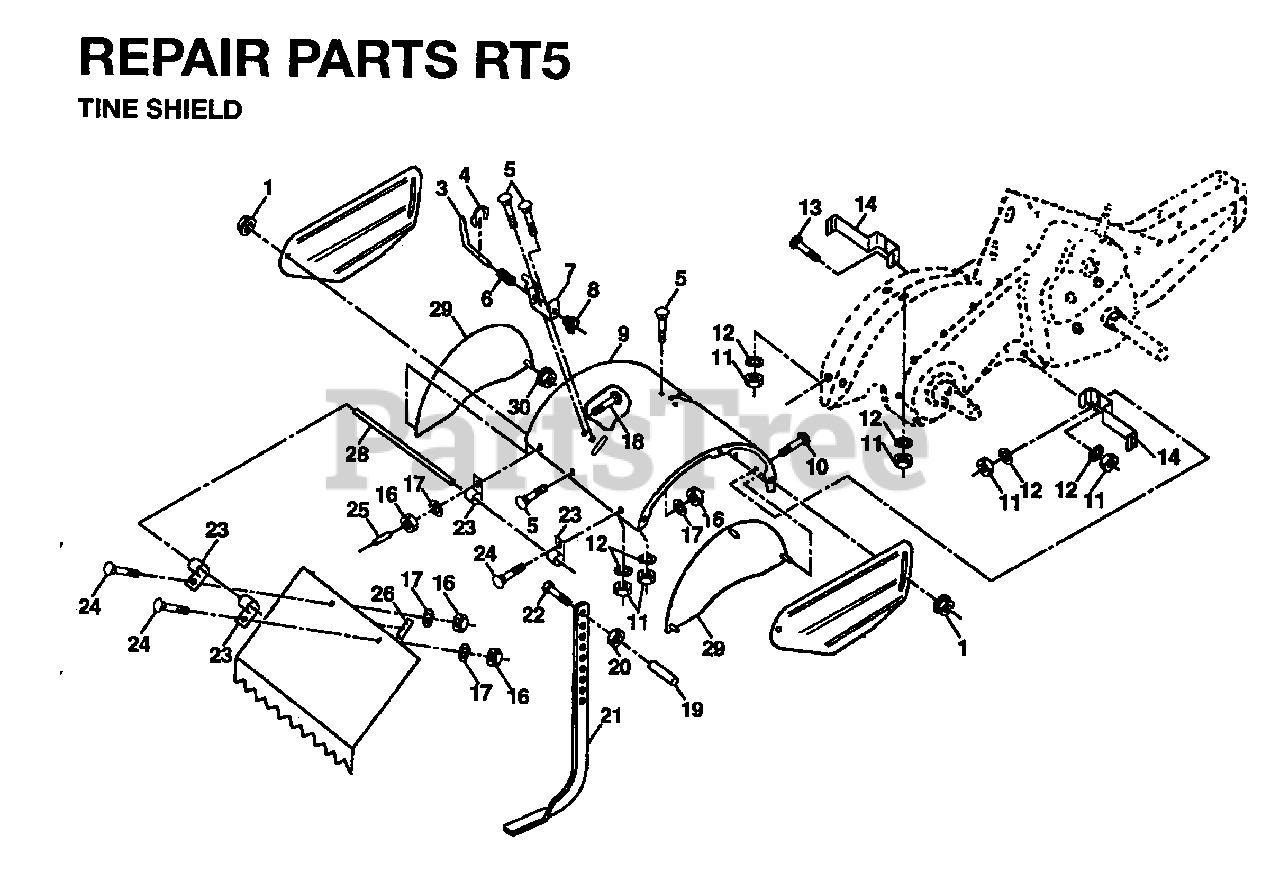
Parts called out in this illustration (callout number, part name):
1	LOCKNUT
3	STAKE PIN TI
4	KLIP RING TI
5	BOLT
6	SPRING TI
7	LATCH BRACKET TI
8	SPRING CRT
10	BOLT
12	LOCKWASHER
13	BOLT.CARRIAGE.5/16-18
14	BRACKET.TINE.SHIELD.TILLER
16	NUT
17	LOCKWASHER
20	NUT.HEX.3/8-16UNC
21	DEPTH STAKE
22	BOLT.375-16
23	HINGE CRT
25	VINYL CAP TI
26	PAD IDLER TI
28	PIN.HINGE.TILLER
30	LOCKNUT
